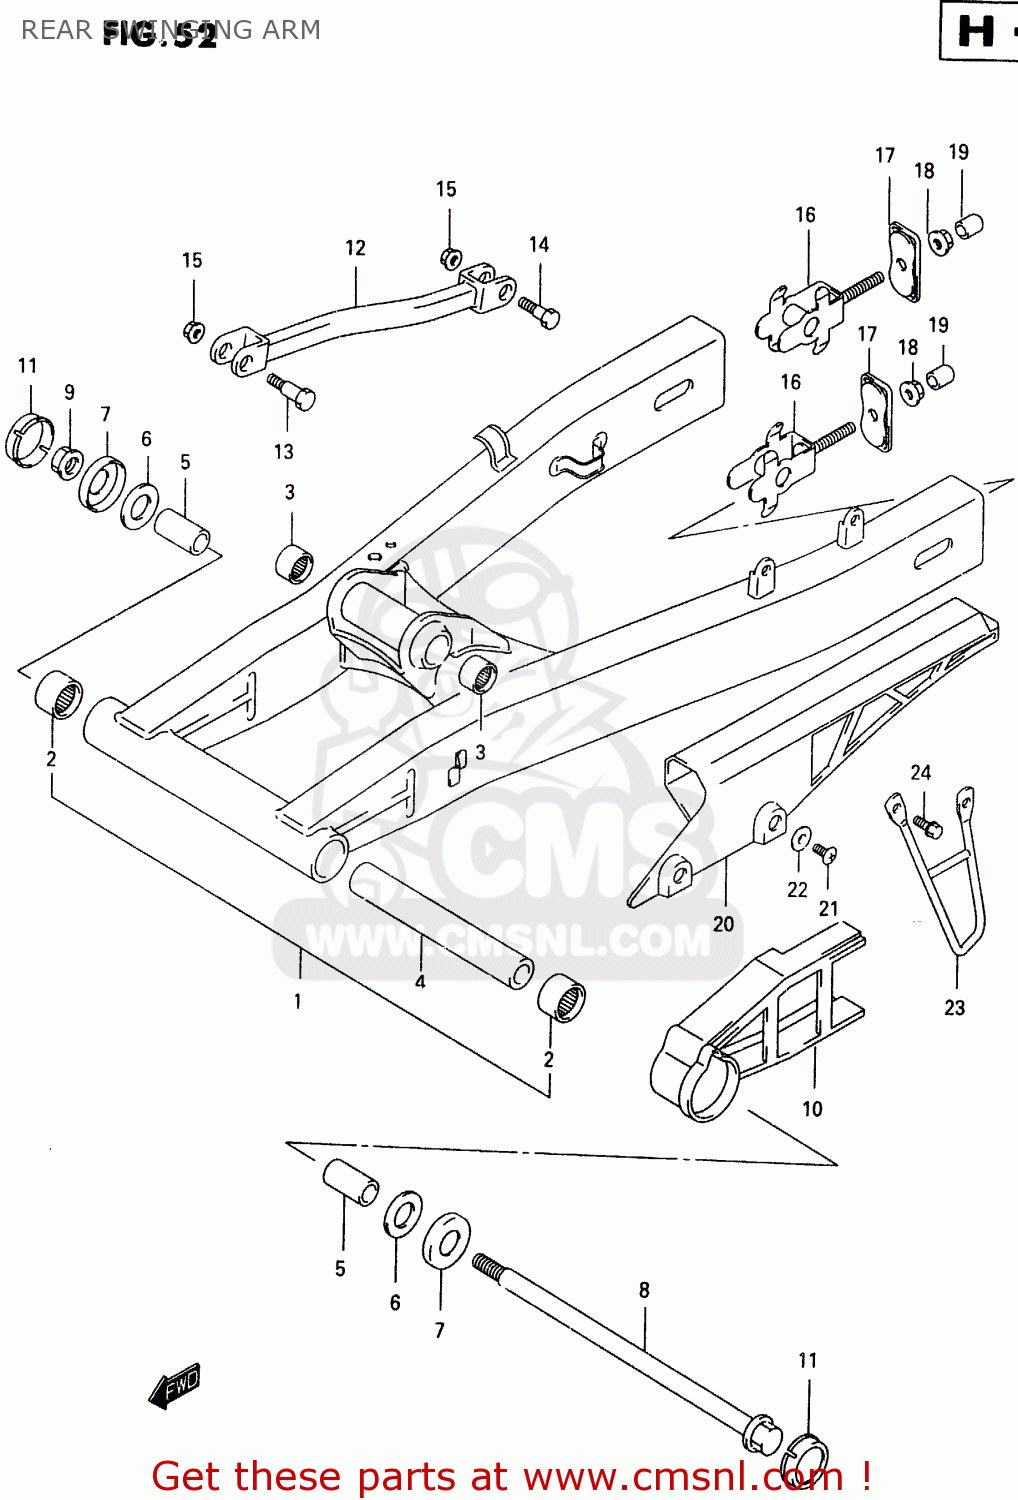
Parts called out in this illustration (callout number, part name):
1	SWING ARM ASSEMBLY,REAR (
2	BEARING(22X29X30)
3	BEARING(20X27X23.5)
4	SPACER,RR SWGARM PIVOT CTR
5	SPACER,RR SWGARM PIVOT
6	WASHER
7	COVER,RR SWGARM DUST SEAL
8	SHAFT,RR SWINGINGARM PIVOT
9	NUT
10	BUFFER,CHAIN TOUCH DEFENSE
11	CAP,SWINGINGARM PIVOT
12	TORQUE LINK COMP,REAR
13	BOLT(10X39)
14	BOLT(10X34)
15	NUT
16	ADJUSTER,CHAIN
17	PLATE,CHAIN ADJ GUIDE
18	NUT
19	CAP,CHAIN ADJUSTER
20	CASE,CHAIN
21	SCREW 6X12
22	WASHER
23	GUARD,CHAIN
24	BOLT
